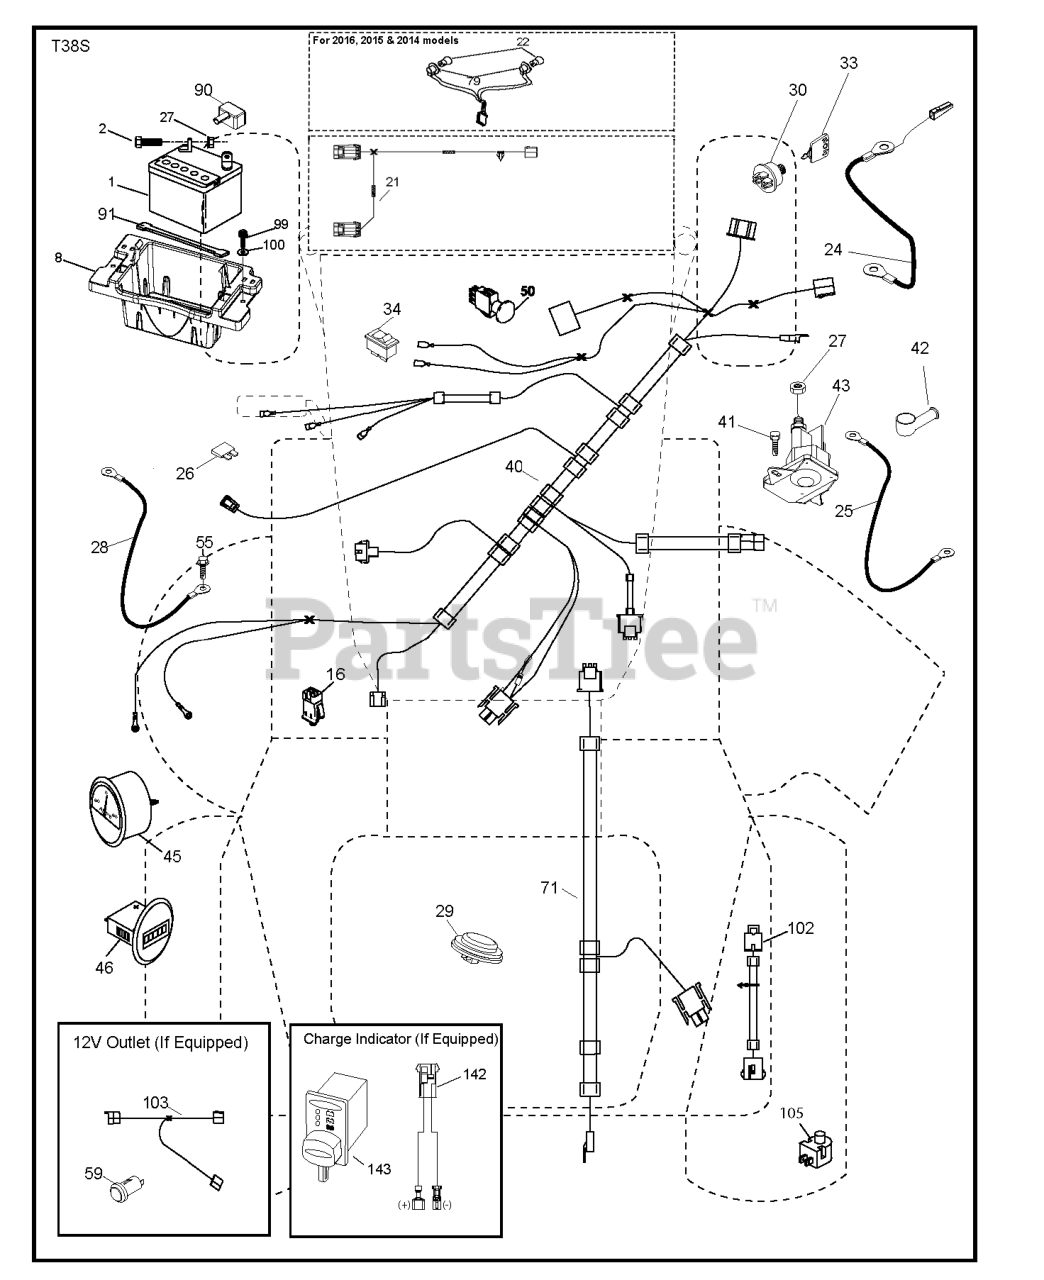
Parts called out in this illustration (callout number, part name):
1	Battery 12 Volt 25 Amp
2	BOLT.HEX.1/4.X.3/4.DICHROMATE
8	TRAY.BATTERY.BOX.FRONT
8	TRAY.BATTERY BOX.FRONT
16	SWITCH INTERLOOK PUSH-IN
21	HARNESS LIGHT ASSY TRACTOR,
22	LIGHTBULB
24	CABLE.FRBATT.W/WIRE.8GA.8
25	CABLE.STARTER.8GA.17.5
26	FUSE 20AMP
27	NUT
28	CABLE.GROUND.21"BLK.8GA.90T
29	SWITCH.SEAT.DELTA.OPC.
30	SWITCH.IGN.DELTA.W.LGH.ROS
33	KEY.CHAIN.BLISTER.PACK.GEN.INT
40	HARNESS.IGN.DSH.W112V.WPORTWIR
40	HARNESS IGN. DASH
41	SCREW
42	TERMINAL COVER
43	SOLENOID.STARTER.BRASS.PLUNGER
45	GAUGE.AMMETER.SILVER/WHITE
46	GAUGE.HOUR.METER.SILVER/WHITE
50	SWITCH.PTO.8TERMINAL.STD.BLK
55	SCREW 5/16"
59	OUTLET.12-VOLT
71	HARNESS-CHASSIS SUB
79	BULB HOLDER ASM.
90	COVER.TERMINAL.BATTERY
91	STRAP.BATTERY.MOUNT.FRONT(2 2)
99	SCREW HEXWSHR 1/4-20X3/4
102	HARNESS PIGTAIL PCH TEX ROS
103	HARNESS.PIGTAIL.12V.OUTLET.
105	REVERSE SWITCH
142	CHARGE.PORT.PIGTAIL HARNESS
143	CHARGE.PORT
